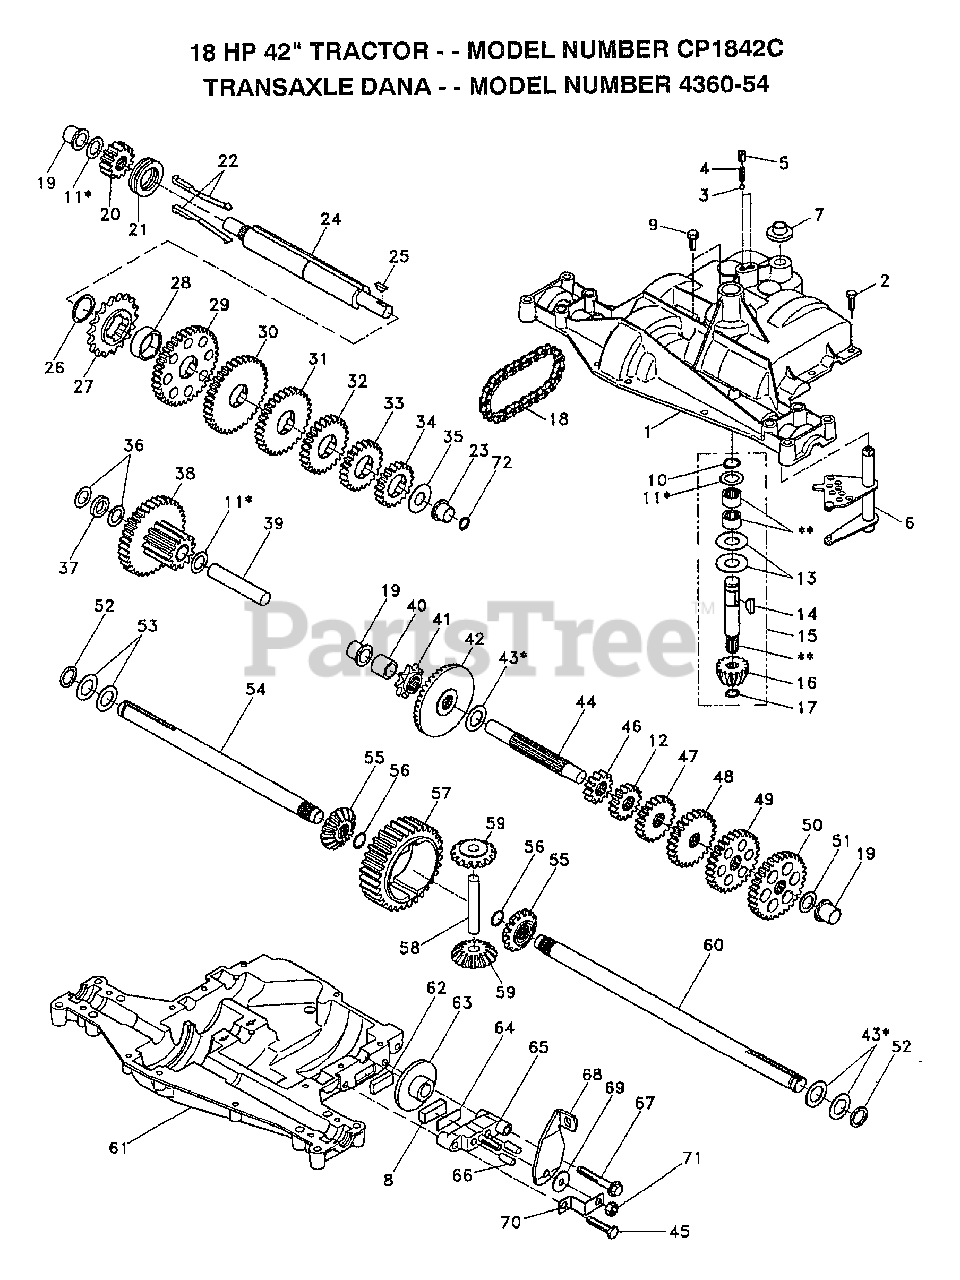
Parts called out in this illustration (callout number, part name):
4	"SPRING, DETENT LT"
5	"SCREW, SET LT"
6	SHIFTER.ASM.KIT.
7	SHIFTER BOOT
8	PUCK T
9	SCREW TAP W/SEAL
10	RETAINING RING LT
11	ASM KIT SHIM 4689
13	WASHER T
14	WOODRUFF KEY
17	"RING,RETAINING LT"
18	"CHAIN,24 PTCH LT"
19	BEARING.FLNG.5510
20	GEAR SPUR 14T
21	COLLAR CLUTCH
22	KIT.ASM.CLUTCH KY
23	"FLANGE, BEARING"
24	SHAFT INTERM
25	WOODRUFF KEY
26	"RING,RETAINING LT"
27	SPROCKET 18T T
28	SPACER YT
29	KIT.GEAR.12/37TH
31	GEAR SPUR 30T
32	GEAR 25T LT
33	GEAR SPUR 22 TT
34	SPUR GEAR 19T
35	"WASHER, PLAIN LT"
36	WASHER 025
37	SPACER
38	ASSM GEAR COMB
39	SHAFT IDLER
40	SPACER T
41	SPROCKET 9T LT
43	ASM KIT SHIM
44	SHAFT T
45	"SCREW, TAPPING LT"
48	"GEAR, SPUR 25T LT"
49	GEAR 28T T
50	"GEAR, SPUR 31T LT"
51	WASHER 060
52	NEOPRENE WASHER
53	WASHER 031
55	GEAR LT
56	"RING,RETAINING LT"
58	SHAFT T
59	"GEAR,MITER 15T YT"
62	PUCK T
63	BRAKE DISC. T
64	SPACER LT
66	PIN T
69	WASHER LT
71	NUT.LOCK.5/16-24
72	SQUARE RING
